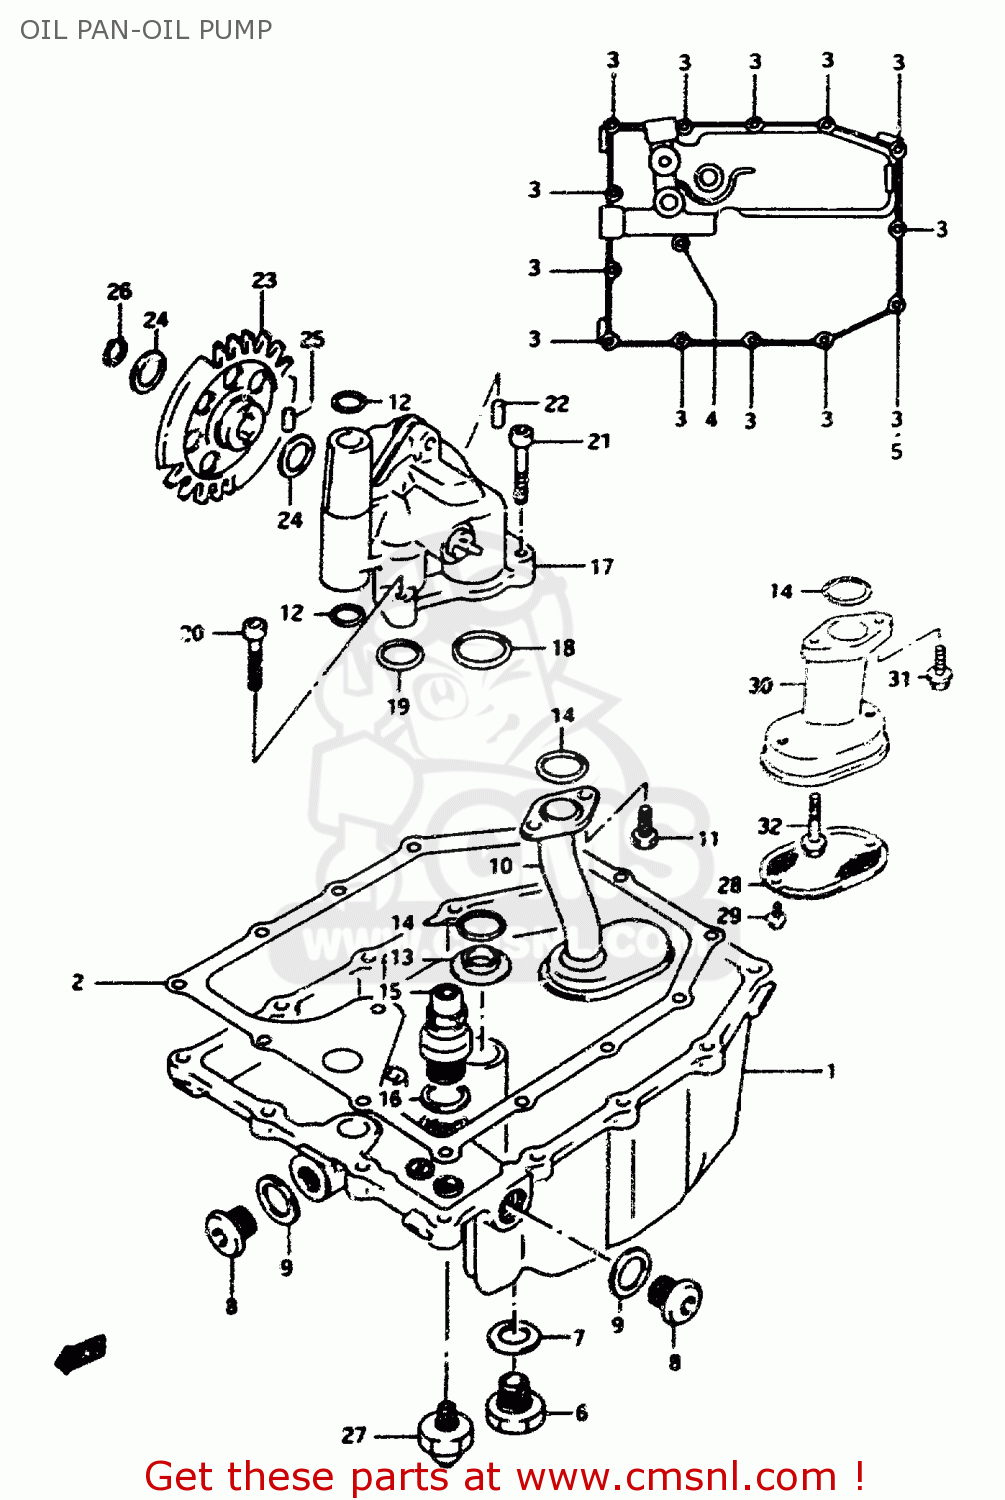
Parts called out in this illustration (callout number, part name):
1	PAN,OIL
2	GASKET,OIL PAN (NAS)
3	BOLT
4	BOLT
5	GASKET(5.8X11X1.2) (NAS)
6	PLUG
7	GASKET(13.8X18.8X4.8) (NAS)
8	PLUG
9	GASKET(16X22X2) (NAS)
10	STRAINER COMP,ENGINE OIL
11	SCREW
12	O RING(D:2.4,ID:11.8)
13	GASKET,OIL OUTLET (NAS)
14	O RING(D:3.2,ID:17.8)
15	VALVE ASSEMBLY,OIL RELIEF
16	GASKET(16X22X2) (NAS)
17	PUMP ASSY,ENGINE OIL
18	O RING(D:2.4,ID:26.2)
19	O RING(D:3.2,ID:17.8)
20	BOLT
21	BOLT
22	PIN
23	GEAR,OIL PUMP DRIVEN(NT:37)
24	SHIM
25	PIN(5X18)
26	CIRCLIP,12 MM
27	SWITCH ASSEMBLY,OIL PRESSURE
28	STRAINER,ENGINE OIL
29	BOLT
30	PROTECTOR,OIL STRAINER
31	BOLT
32	BOLT, HYDRAULIC UNIT NO.2
